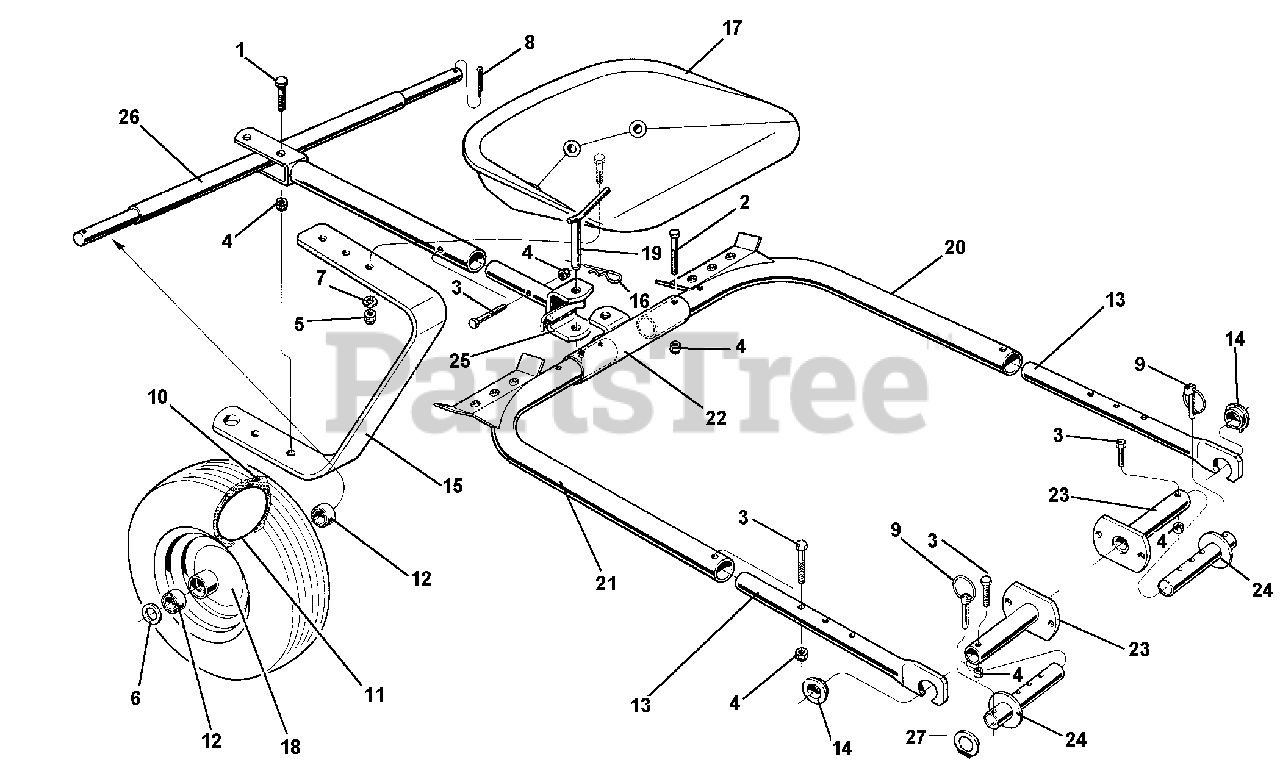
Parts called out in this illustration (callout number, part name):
1	SCREW M10 X 30
2	SCREW TE M10 X 65 UNI 5739-8G
4	NUT, SELF LOCKING M10
5	NUT, SELF LOCKING M12 LOW
6	WASHER, FLAT 26
7	WASHER, LOCK 13
8	PIN, COTTER Z 5 X 40 UNI 1336
10	TIRE FOR CAR 100 X 203
11	TUBE 4.00 X 8
15	SEAT SPRING
17	PADDED SEAT
18	SULKY WHEEL
20	SULKY HALF FRAME
21	SULKY HALF FRAME
22	SULKY COUPLING
24	WHEEL EXTENSION
25	FORK COUPLING
27	SPACER WASHER (SEE NOTE FOR ITEM #24)
